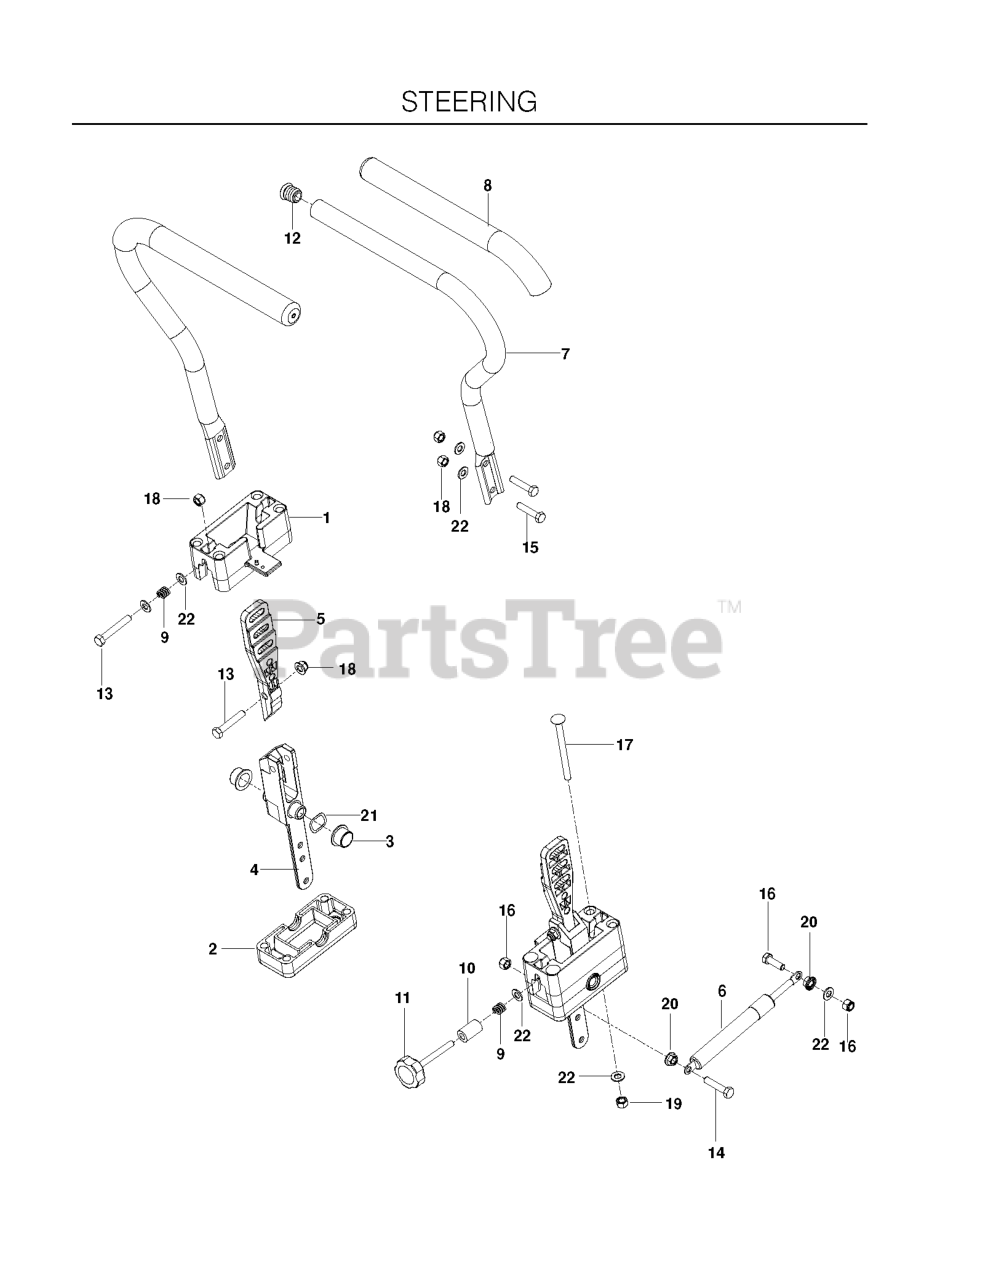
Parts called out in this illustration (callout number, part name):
1	BLOCK, UPPER
2	BLOCK, LOWER
3	BEARING, FLANGE
4	PIVOT SECTION, DRIVE CONTROL
6	DAMPENER
7	LEVER, DRIVE - W/GRIP
8	GRIP, FOAM (GROUND) 15
12	END PLUG 15/16` (BLACK)
13	HCS 5/16-18 X 2 TPBLT GR 5 ZD
14	HCS 5/16C X 1
15	CAPSCREW 5/16 X 1/1/2 HEX HEAD
16	HCS 5/16C X 1 3/4
17	RHSNB 5/16-18 X 4 GR 5 ZD
18	5/16-18 NYLOC FLANGE NUT
19	NUT 5/16 NYLOC
20	NUT 5/16C WHIZ
21	WASHER, .825 X 1.087, WAVE
22	FLAT WASHER 5/16 SAE
